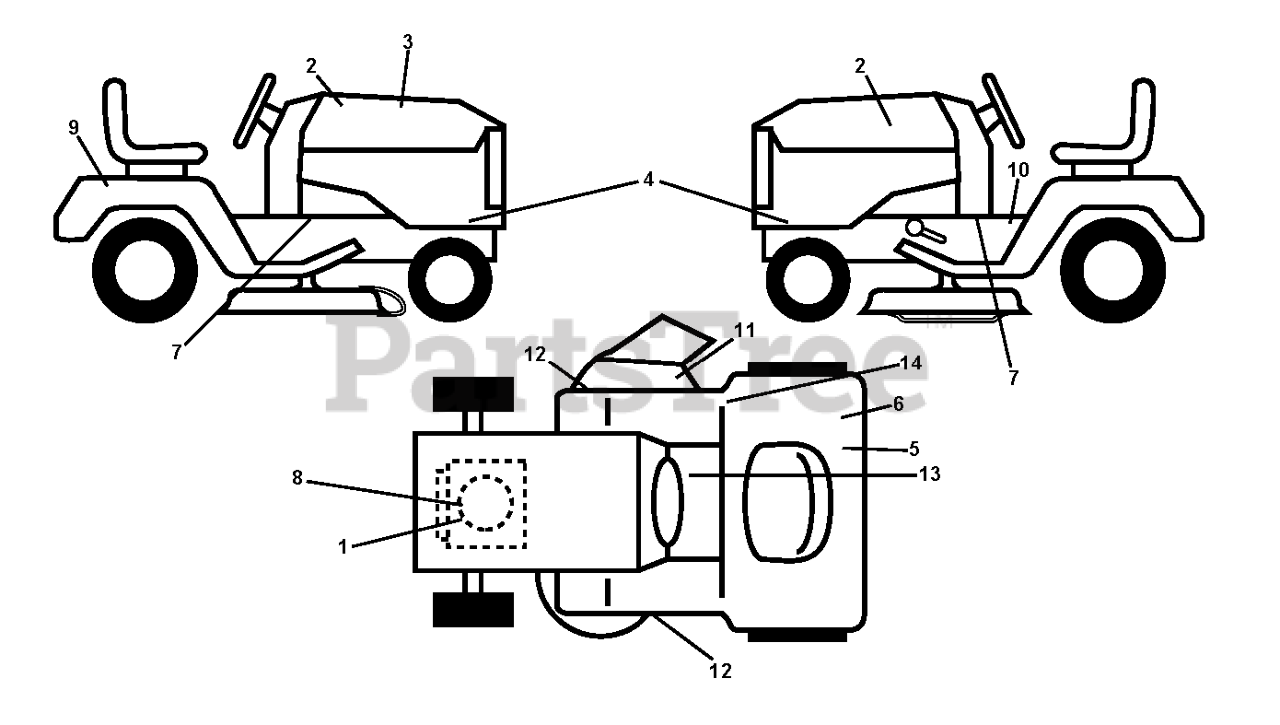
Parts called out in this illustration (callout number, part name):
1	DECAL
2	DECAL.HOOD.LOGO.ORANGE.HUSQVAR
3	Decal, Rpl
5	DECAL
6	DECAL
9	DECAL BTRY SYMBOLS
10	LABEL
11	DECAL.WARN.DFLECT/CTFINGR.SRD
12	Decal, Mower V-Belt Schematic
13	DECAL PARK BRAKE
14	Decal, Fender 100 DB/CE
